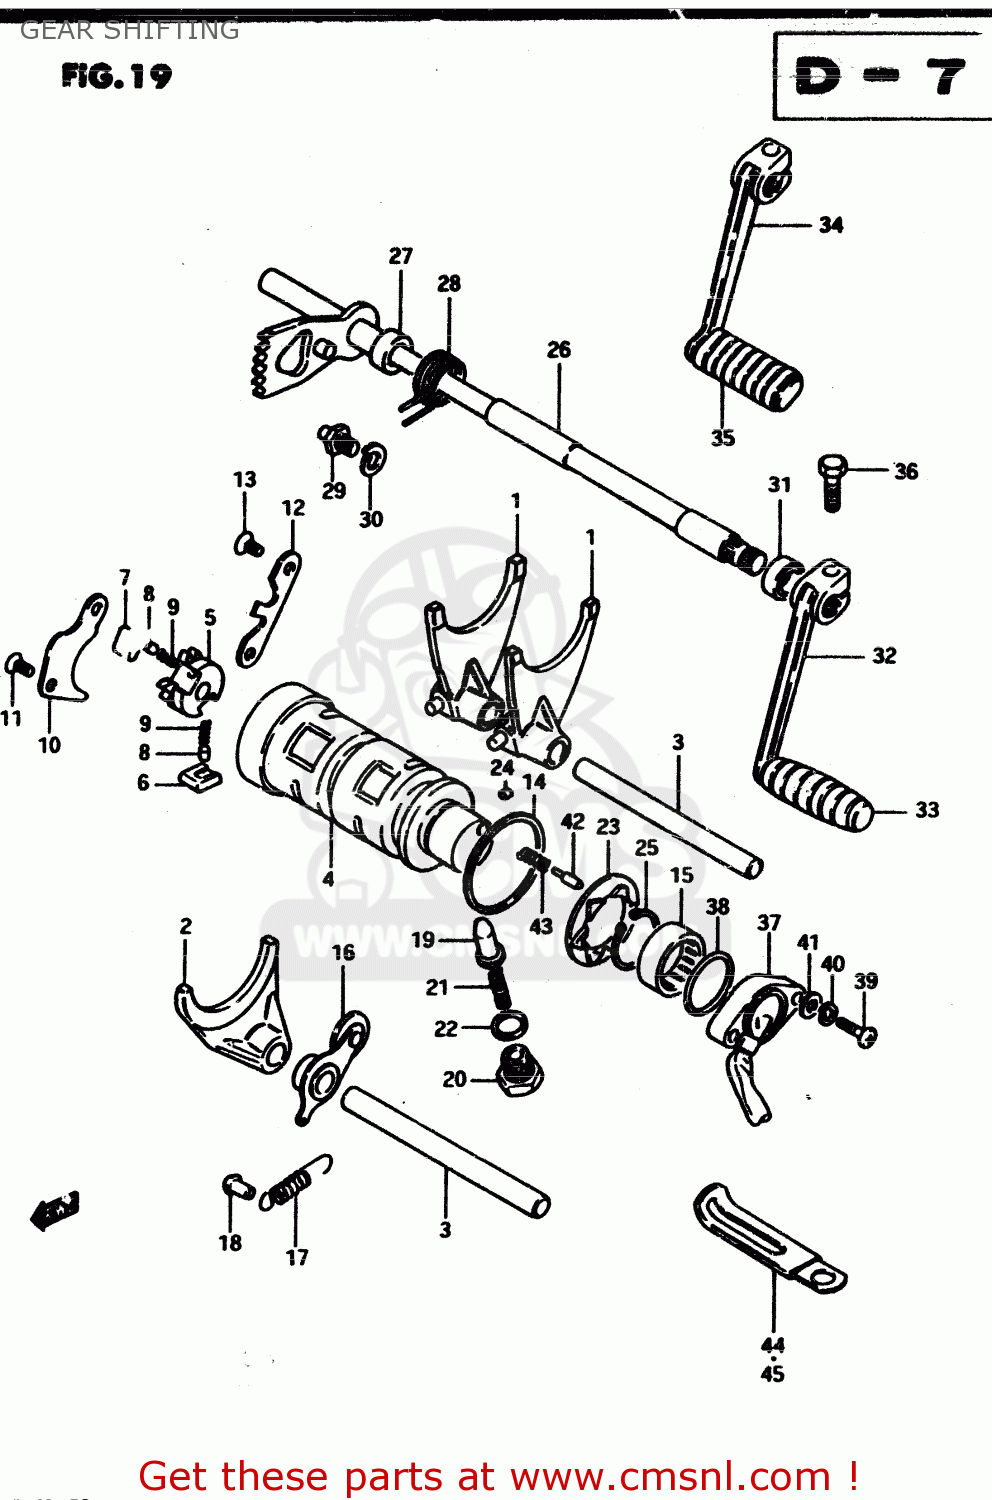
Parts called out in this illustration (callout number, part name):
1	FORK,GEAR SHIFT NO.1
2	FORK,GEAR SHIFT NO.3
3	SHAFT,GEAR SHIFT FORK
4	CAM,GEAR SHIFT
5	RETAINER,GEAR SHIFT CAM
6	PAWL,GEAR SHIFT NO.1
7	PAWL,GEAR SHIFT NO.2
8	PIN(5X8)
9	SPRING
10	LIFTER,GEAR SHIFT PAWL
11	SCREW
12	GUIDE,GEAR SHIFT CAM
13	SCREW
14	WASHER(40X45X1)
15	BEARING
16	STOPPER,GEAR SHIFTING
17	SPRING
18	RIVET
19	STOPPER,GEAR SHIFT CAM NO.2
20	HOLDER,GEAR SHIFT CAM STOP SPR
21	SPRING
22	GASKET(14X19.2X2) (NAS)
23	PLATE,GEAR SHIFT CAM STOPPER
24	PIN 4X6
25	CIRCLIP,25MM
26	SHAFT,GEAR SHIFT
27	SPACER (12X20X12)
28	SPRING
29	STOPPER,GEAR SHIFT CAM
30	WASHER
31	OIL SEAL
32	LEVER ASSEMBLY,GEAR SHIFTING
33	RUBBER,GEAR SHIFT PEDAL
34	LEVER ASSEMBLY,GEAR SHIFTING
35	RUBBER,PEDAL
36	BOLT
37	TERMINAL BASE ASSY,GEAR SHIFT
38	O-RING (D:2.4 ID:26.2)
39	SCREW 5X20
40	LOCK WASHER
41	WASHER
42	PIN(5X15.5)
43	SPRING
44	CLAMP L:35
45	CLAMP
